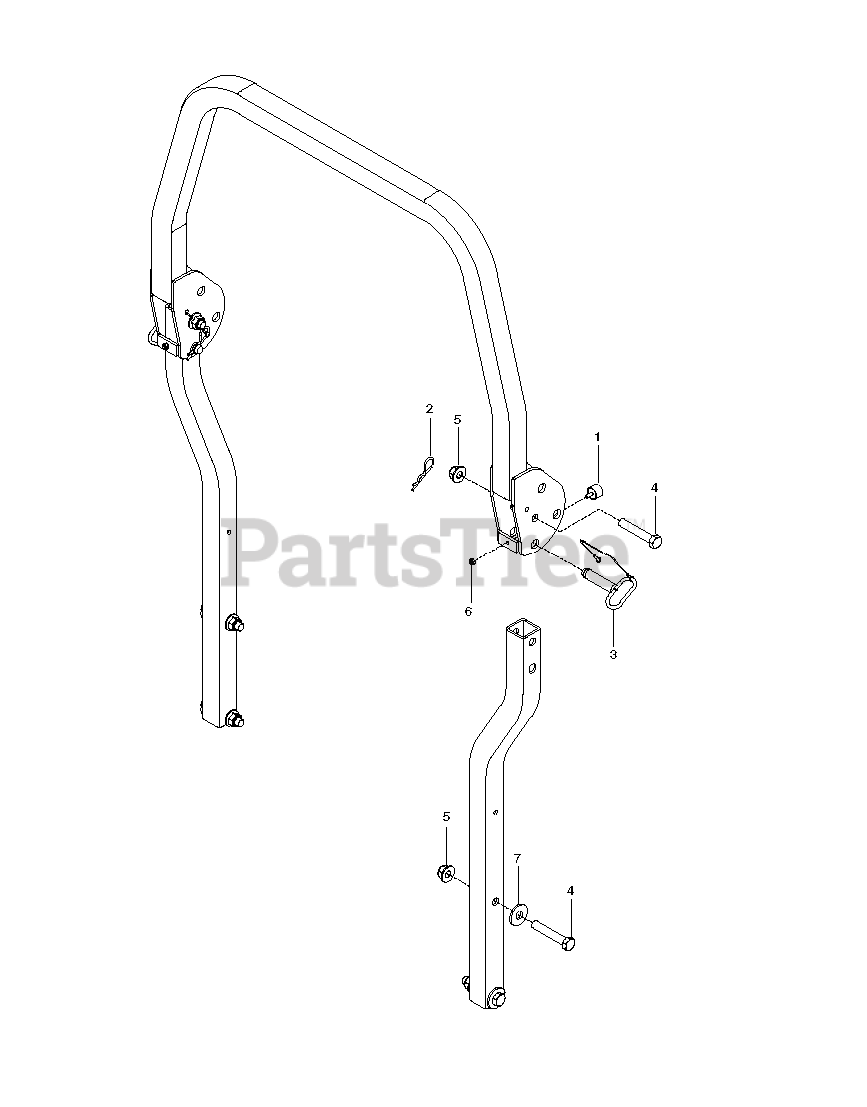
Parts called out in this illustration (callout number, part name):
2	PIN HAIR .148 X 2-15/16 #210
3	BUMPER, MALE STUD, 1/4-20
4	5/8-11 X 3-1/2 HHB GRADE 5
5	NUT.1/4-20.HEX.NYLOC.ZD
6	NUT 5/8-11 FLG NYLOC ZD
7	WASHER, 5/8 FLAT
